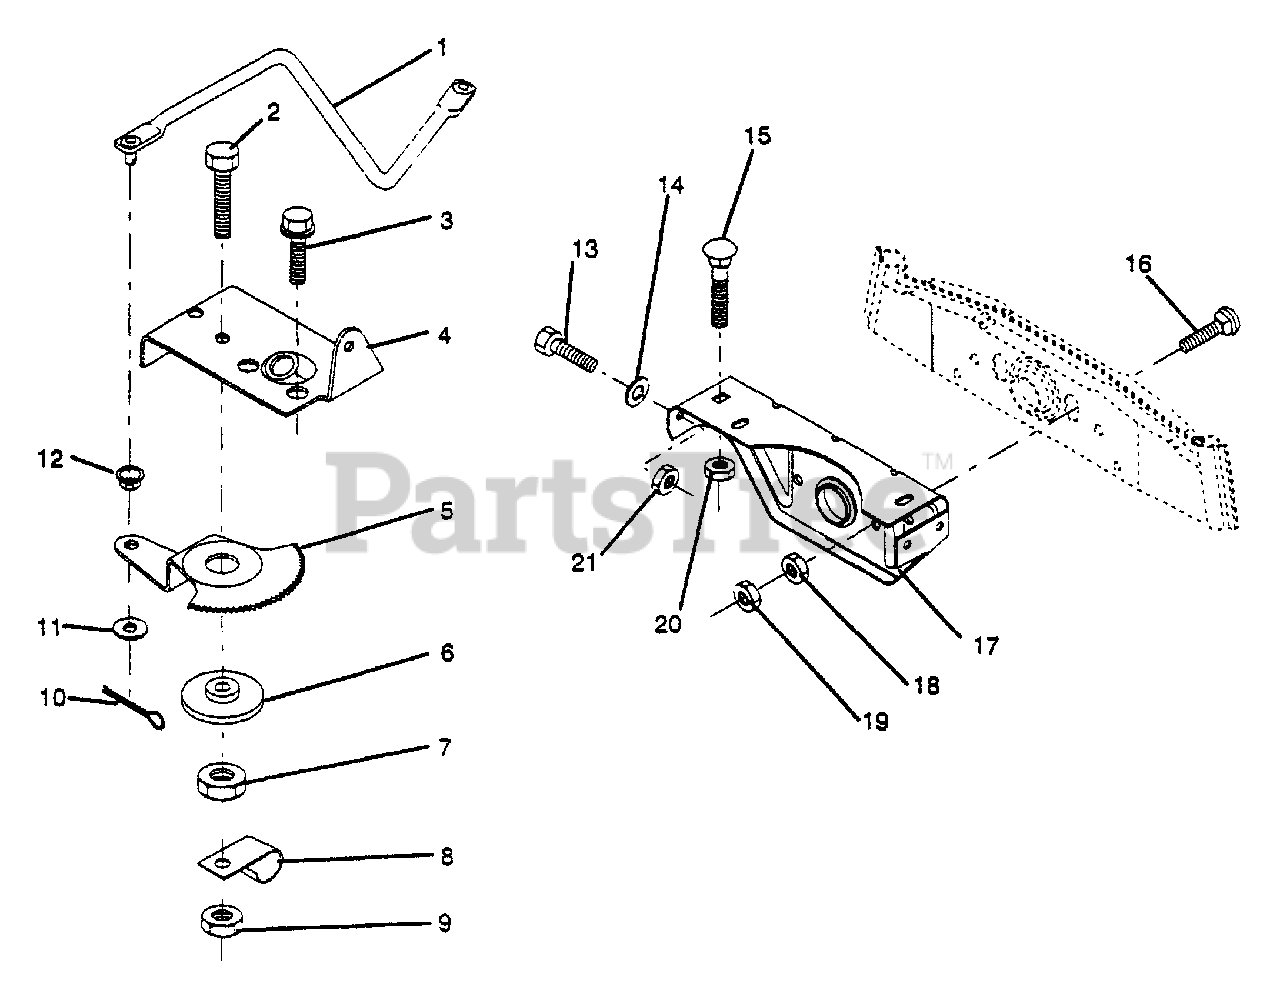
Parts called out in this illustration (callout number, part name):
1	Link, Drag
2	Bolt, Fin. Hex 1/2-13 x 1 3/4
3	Screw Hex Washer Hd. Thrdrol 5/16-18 x 1/2
4	Plate,Steering Support
5	Gear, Sector
7	Nut, Heavy Hex Top Lock 1/2-13 UNC
8	Clip, Insulated
9	Nut, Crownlock 1/2 x 13 UNC
10	Pin, Cotter 1/8 x 3/4
11	Washer, 13/32 x 13/16 x 16 Ga.
13	Bolt, Hex Hd. 5/16-18 UNC x 3/4
14	Washer 11/32 x 7/8 x 16 Ga.
15	Bolt, Carriage 3/8-16 UNC x 3/4
16	Bolt, Carriage
17	Support, Front Axle
18	Nut, Fin. Hex 3/8-16 UNC
19	Nut, Centerlock 3/8-16 UNC
20	Nut, Crownlock 3/8-16 UNC
21	Nut, Crownlock 5/16-18
